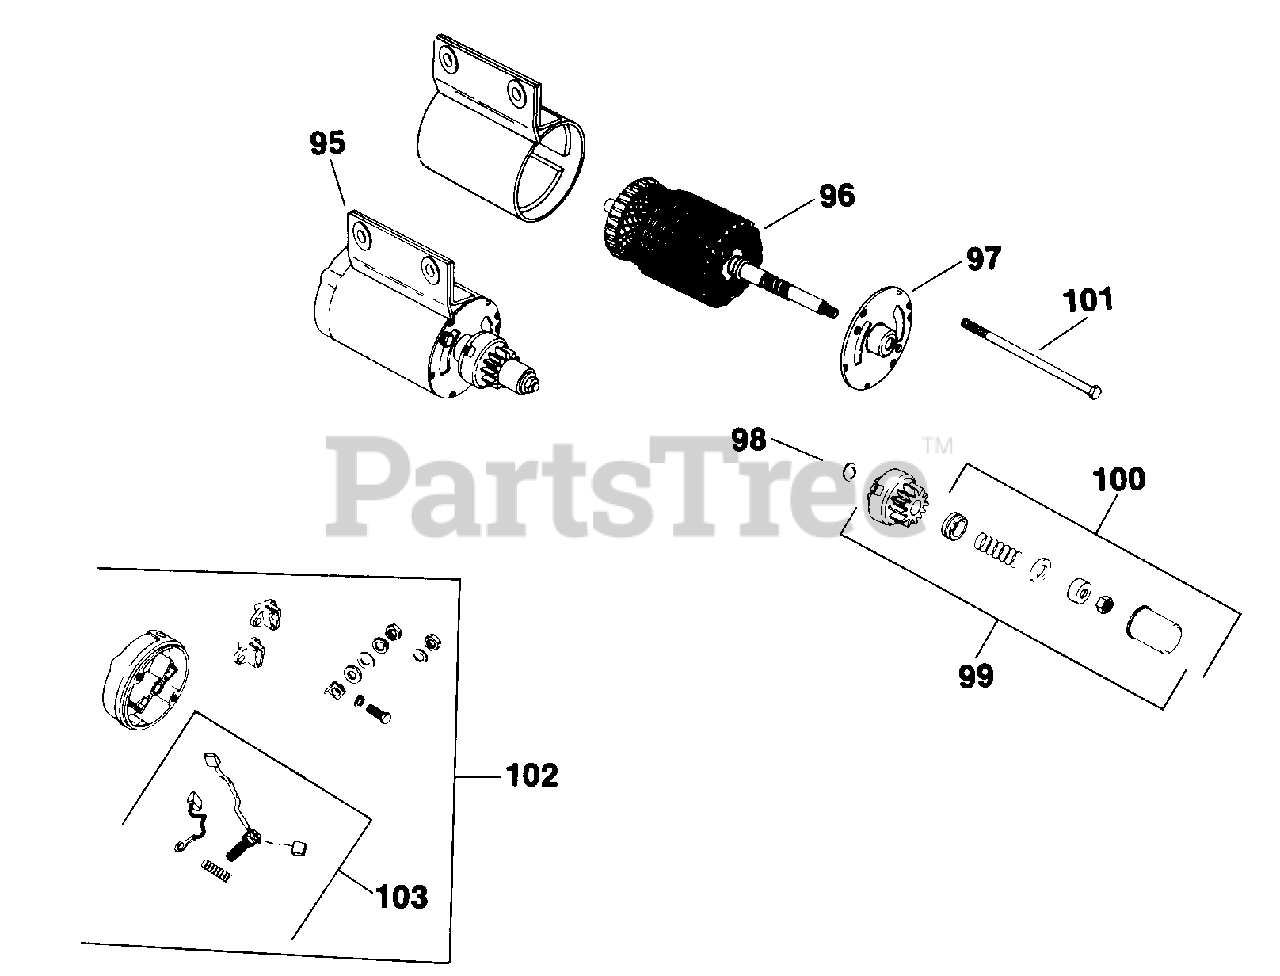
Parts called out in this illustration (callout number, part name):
95	STARTER - USE 41 098 03
97	CAP - USE 45 081 05
98	WASHER - DISCONTINUED
99	DRIVE KIT - USE 41 755 34
102	CAP - DISCONTINUED
103	KIT - USE 52 755 15
